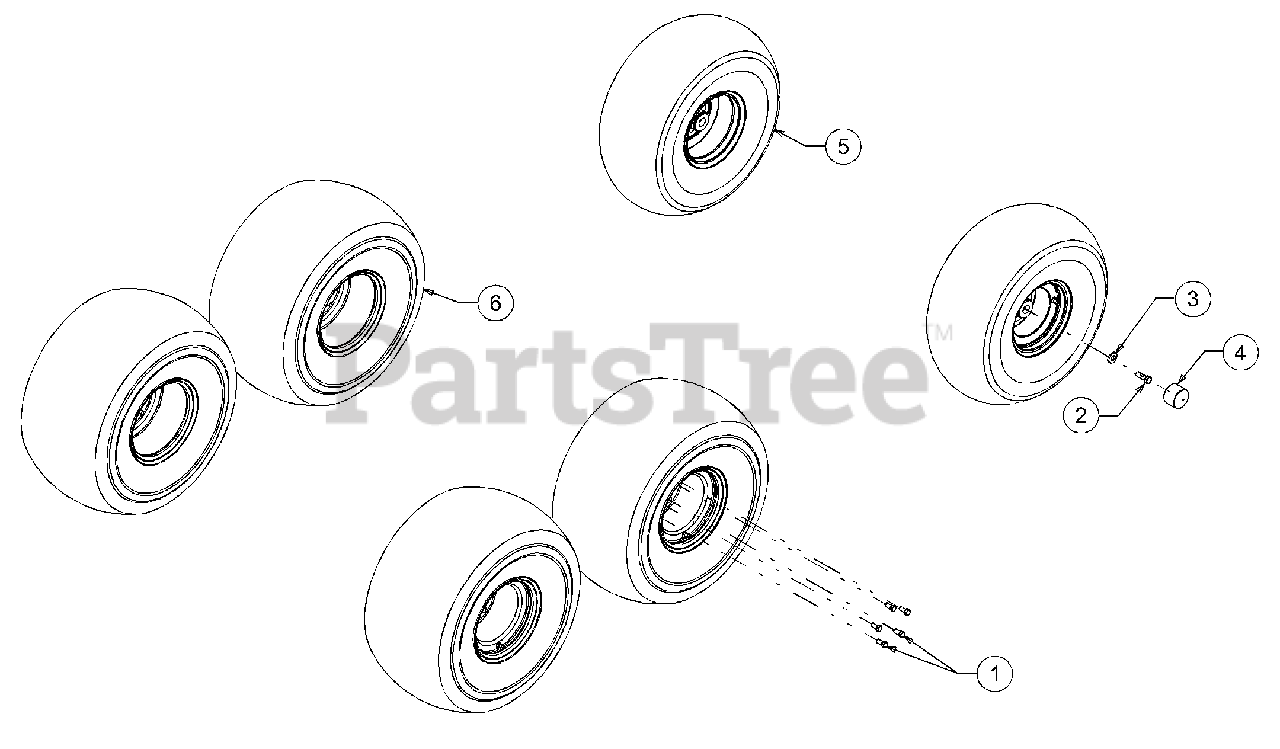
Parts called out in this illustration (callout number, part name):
1	Hex Screw, 7/16-20 x 1.5, Gr5
2	Hex Screw, 1/2-13 x 1.5, Gr5
3	Washer, Flat, .531 x 1.25 x .181
4	Dust Cover
5	Wheel Assembly, RH 22 x 11 x 10 EMT (AT)
5	Wheel Assembly, LH 22 x 11 x 10 EMT (AT)
6	Wheel Assembly, RH 25 x 11 x 10 EMT (AT)
6	Wheel Assembly, LH 25 x 11 x 10 EMT (AT)
